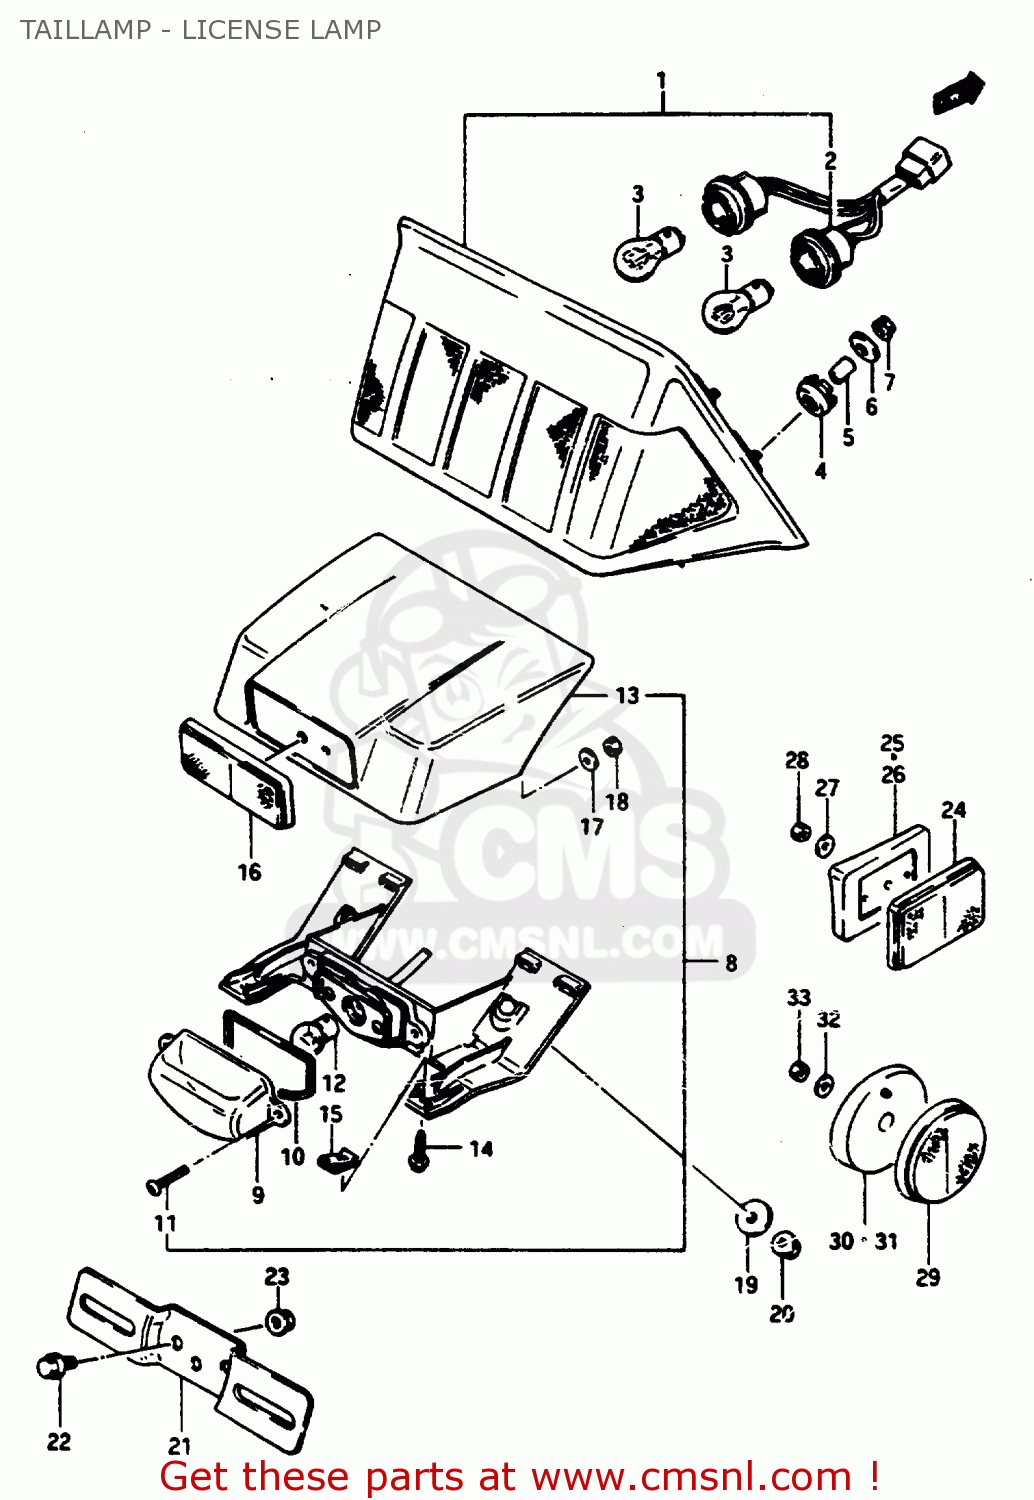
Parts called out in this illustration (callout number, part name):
1	LAMP ASSY, REAR COMBINATION
2	SOCKET,REAR COMBINATION LAMP
3	BULB(12V21/5W)
4	CUSHION
5	SPACER (6.4X9X13.5)
6	WASHER
7	NUT
8	LAMP ASSY, LICENSE
9	LENS,LICENSE LAMP
10	GASKET,LICESE LAMP (NAS)
11	SCREW
12	BULB
13	COVER,LICENSE LAMP
14	SCREW
15	COVER,TURN,RIGHT
16	REFLEX REFLECTOR,REAR
17	WASHER(5.2X16X1)
18	NUT
19	WASHER
20	NUT
21	BRACKET,LICENSE PLATE
22	BOLT
23	NUT
24	REFLECTOR,REFLEX
25	SPACER, RH
26	SPACER, LH
27	WASHER(5.2X16X1)
28	NUT
29	REFLEX REFLECTOR ASSY,FR
30	SPACER, RH
31	SPACER, LH
32	WASHER(5.2X16X1)
33	NUT
